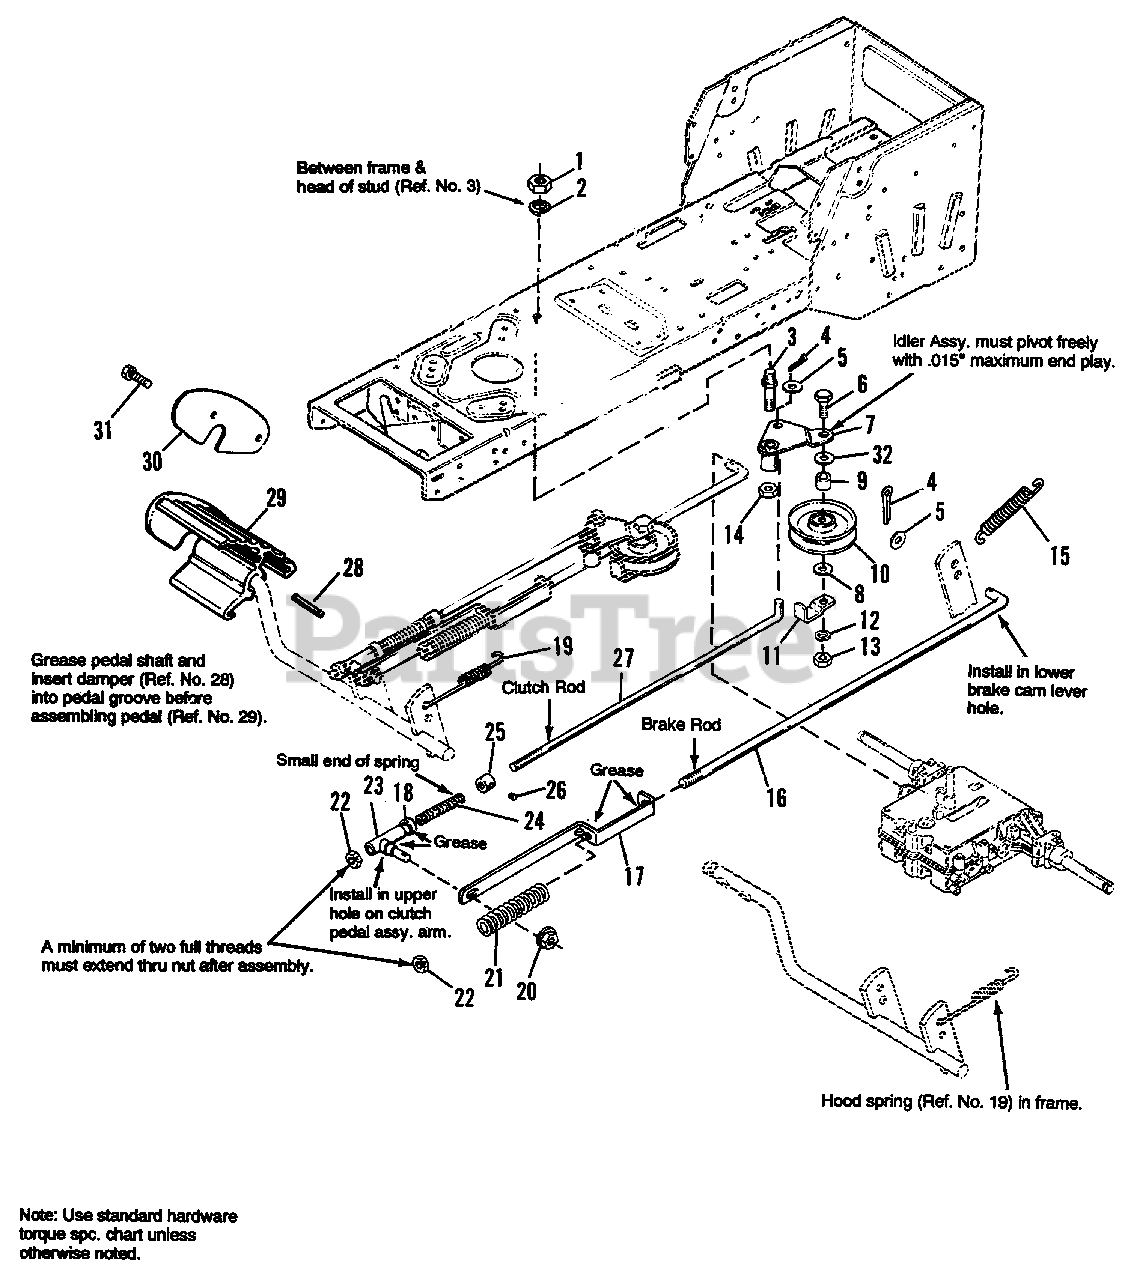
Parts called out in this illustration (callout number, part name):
1	NUT, Hex, 7/16-14
2	LOCKWASHER, 7/16
4	PIN, Cotter
5	WASHER, 11/32
6	CAPSCREW, 3/8-16 x 1-1/2
7	IDLER ASSY.
8	WASHER, Plain, 5/16
10	PULLEY ASSY.
11	GUARD, Spring
12	LOCKWASHER, 3/8
13	NUT, Hex, 3/8-16
14	LOCKNUT, Hex, 7/16-14
15	SPRING, Tension
19	SPRING, Return
20	LOCKNUT, Hex, Flange, 5/16-18
22	LOCKNUT, 5/16-18
23	GUIDE ASSY., Rod
24	SPRING, Compression
25	COLLAR, Set
26	SETSCREW, 1/4-20 x 3/8
27	ROD, Clutch
28	DAMPER, Rubber
29	PEDAL, Foot
30	PLATE, End
31	SCREW, Taptite, 1/4-20 x 5/8
32	WASHER, Plain
